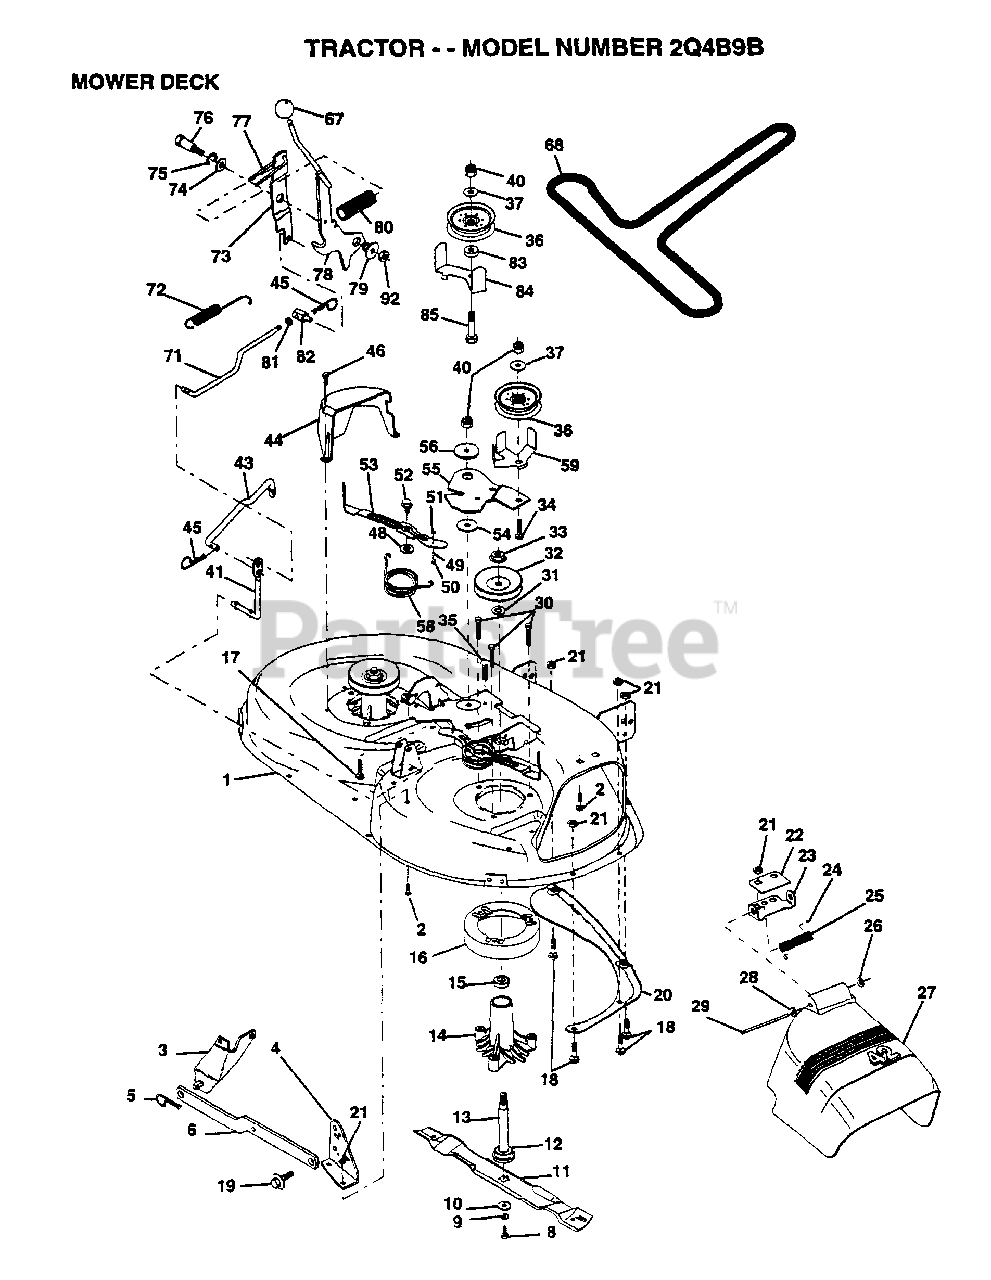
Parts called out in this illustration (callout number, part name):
1	DECK.WELD.42.
2	BOLT
3	BRKT ASM SWAY BAR
4	BRKT DECK SW BAR
8	BLADE BOLT
10	WASHER.HARD.BLADE
11	"BLADE.42"" HIPERF"
12	BEARING.BALL
14	HSG ASM MANDREL
15	BEARING
16	STRIPPER RND MWR
17	BOLT RDHD 3/8-16
18	BOLT
19	BOLT SHD 5/16-18
22	STIFFENER BRKT
23	DEFLECTOR BRKT
24	CAP-SLEEVE LT
25	SPRING TORSION
26	NUT PUSH M
27	DEFLECTOR.SHIELD
28	WASHER
29	HINGE ROD
31	WASHER
34	BOLT
35	XMAS TREE FASTNER
36	FLAT IDLER PULLEY
37	WASHER
41	PIVOT ROD
43	ROD CLUTCH W/NIBS
44	GUARD MAND LH BLK
45	RETAINER M
46	SCREW.1/4-20X5/8
48	HARD SMALL WASHER
50	SHOULDER BOLT
51	LOCKNUT
52	BOLT.SHLD.5/16-18
53	BRAKE PAD ARM ASM
54	HARDENED WASHER
56	SPACER RETAINER
58	SPRING TORSN BRAK
59	GUARD IDLER TUV
67	KNOB T(3/8 HOLE)
68	BELT.V.T-PATH
71	ROD CLUTCH 38/42
72	RETURN SPRING
73	CLUTCH ARM SECOND
74	WASHER
75	RING
76	SHOULDER BOLT
77	SPRING KEEPER
79	BUSHING
81	NUT
82	TRUNION ADJ
83	WASHER
85	BOLT
92	NUT
